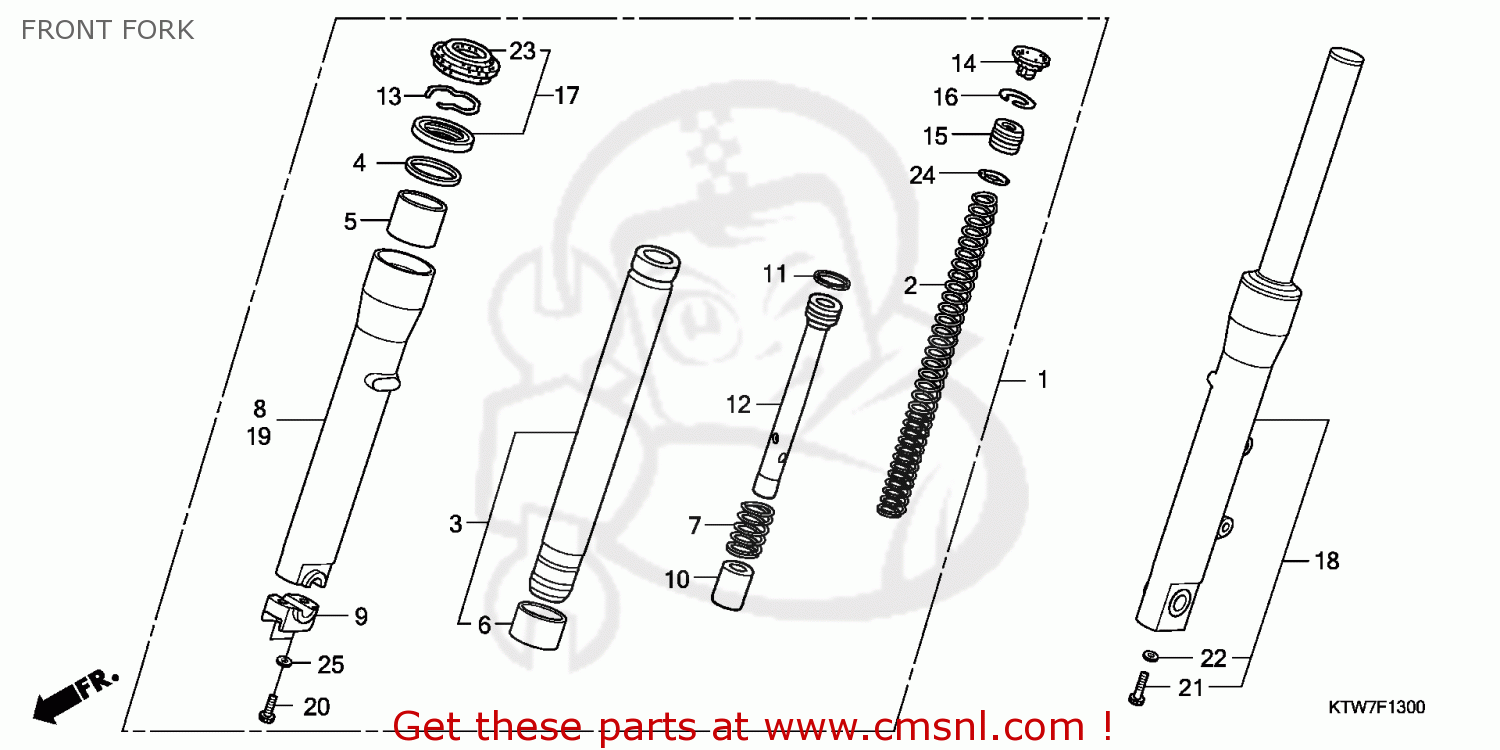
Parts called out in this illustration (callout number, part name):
1	FORK ASSY,R FRONT
2	SPRING,FR FORK
3	PIPE COMP,FR FORK
4	RING,BACK UP
5	BUSH,GUIDE
6	BUSH,SLIDER
7	SPRING,REBOUND
8	CASE,R FR BOTTOM
9	HOLDER,FR AXLE
10	PIPE,OIL LOCK
11	RING,PISTON
12	PIPE,SEAT
13	RING,OIL SEAL STO
14	CAP,FORK PIPE
15	SEAT B,SPG
16	RING,STOPPER
17	SEAL SET,FR FORK
18	FORK ASSY,L FRONT
19	CASE,L FR BOTTOM
20	BOLT,SOCKET 8X30
21	BOLT,SOCKET 8MM
22	WASHER,SPL.,8MM
23	SEAL,DUST
24	O RING 26.2X2.4
25	WASHER,PLAIN 8MM
